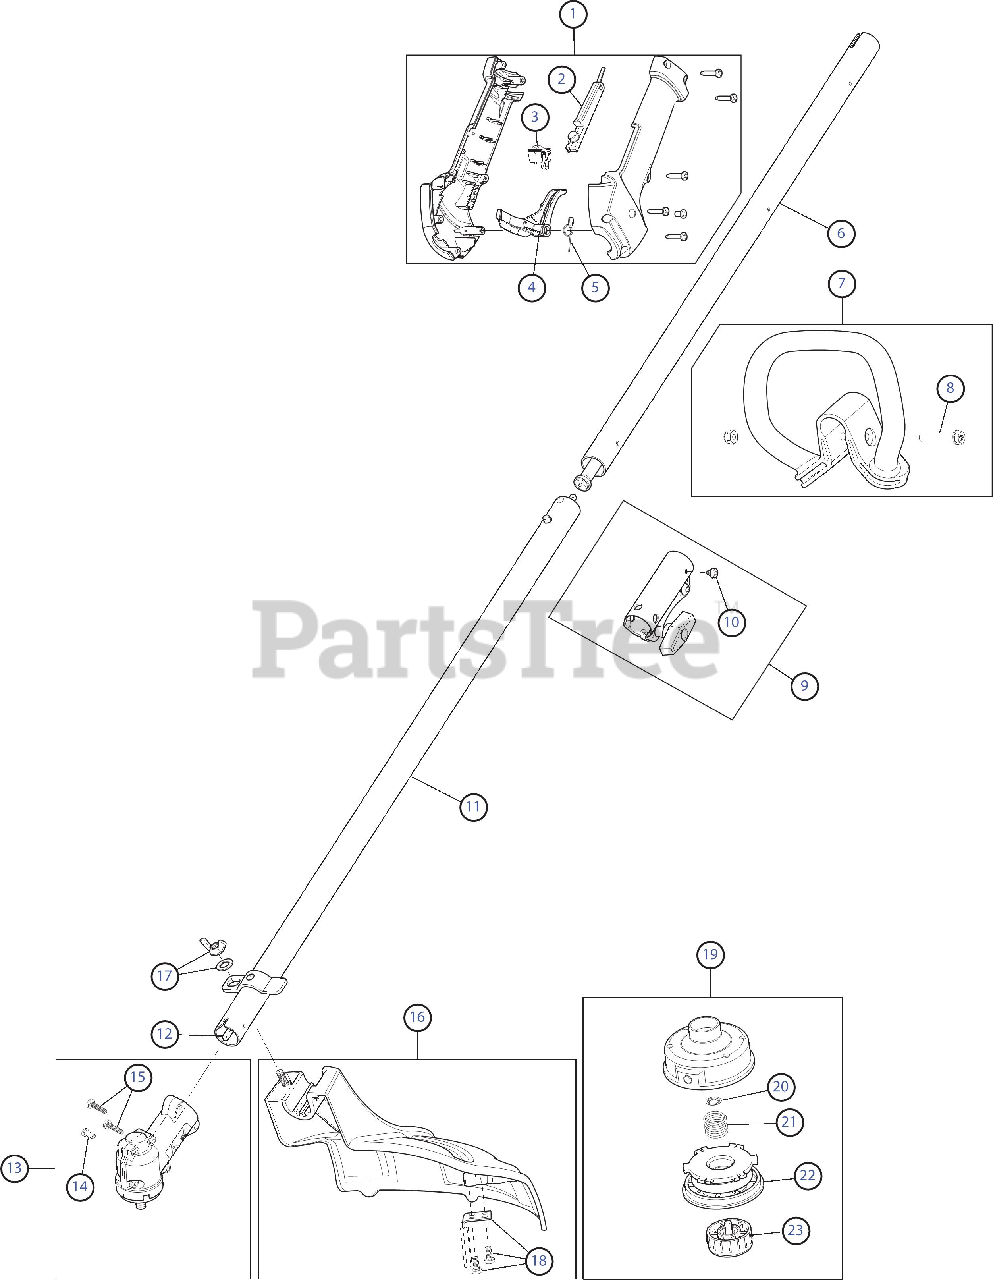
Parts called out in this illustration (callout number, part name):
1	Throttle Housing Assembly (Incl. 2 - 5)
2	Throttle Trigger Lock-Out
3	Throttle Switch Assembly
4	Throttle Trigger
5	Throttle Trigger Spring
6	Upper Shaft Housing Assembly
7	D-Handle (Incl. 8)
8	D-Handle Bolt
9	Split Boom Coupler (Incl. 10)
10	Coupler Anti-Rotation Screw
11	Lower Shaft Housing Assembly
12	Lower Flexible Drive Shaft
13	Gearbox Assembly (Incl. 14 & 15)
14	Gearbox Anti-Rotation Screw
15	Gearbox Mounting Hardware
16	Shield Assembly (Incl. 17 & 18)
17	Shield Mounting Hardware
18	Blade Assembly
19	Outer Spool Assembly (Incl. 20 - 23)
22	Inner Reel
23	Bump Knob Assembly
